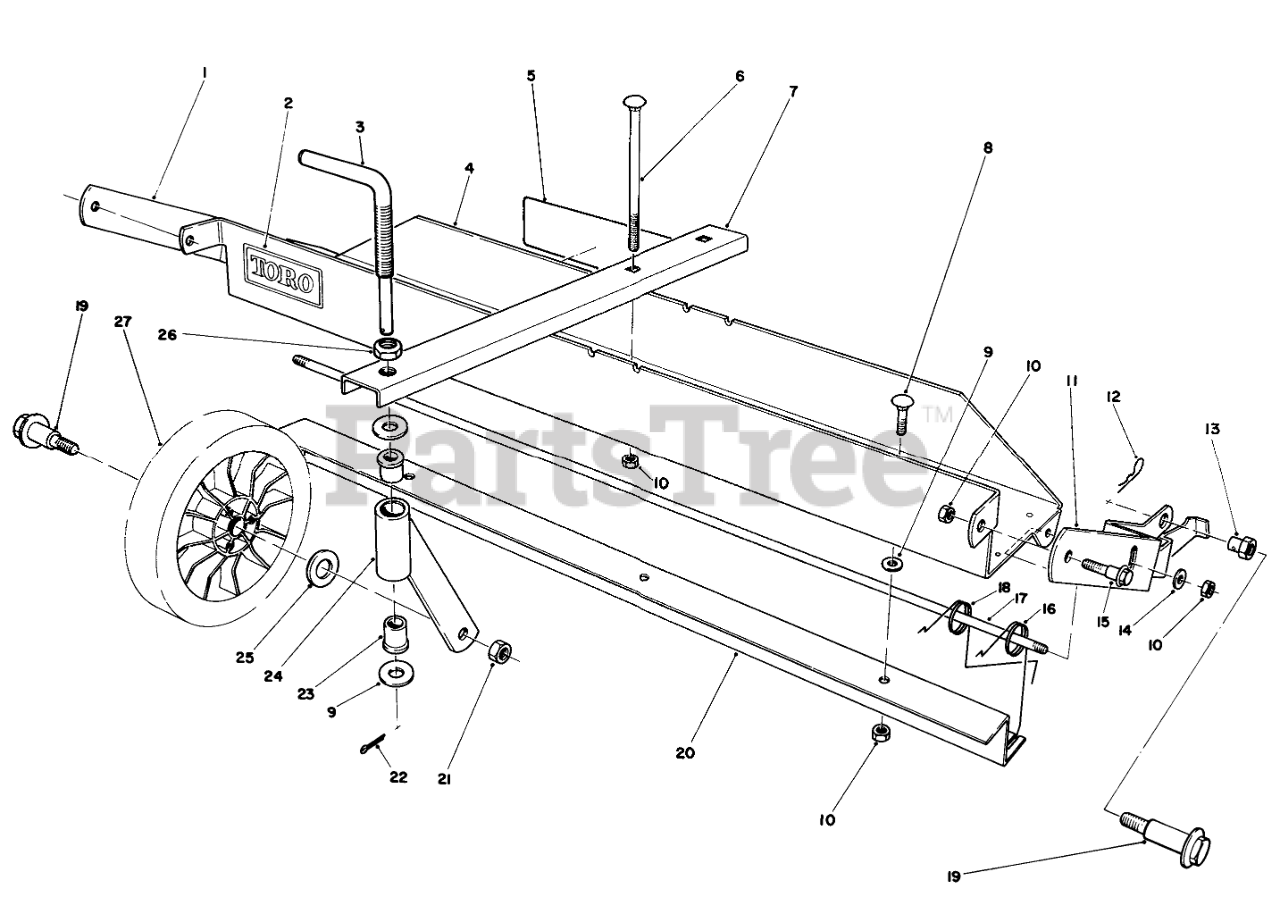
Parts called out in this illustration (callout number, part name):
1	Frame R.H.
2	Decal-Toro
3	CASTOR ADJ ROD
4	Frame-Main (Incl. Ref. #2)
5	Decal-Instruction
6	SCREW-CARR
7	Castor Frame
8	BOLT-CARR
9	WASHER-PLAIN
10	NUT-HEX, SIDE DEFORM
11	LH MTG FRAME
12	PIN-COTTER, HAIR
13	PIVOT NUT
14	WASHER-FLAT
15	BOLT-SHOULDER
16	DETHATCHER SPRING
17	SPRING SUPPORT ROD
18	DETHATCHER SPRING
19	BOLT-WHEEL
20	SPRING GUIDE STRAP
21	NUT-LOCK
22	PIN-COTTER
23	FLANGE BUSHING
24	Castor Tube & Support
25	WASHER
26	NUT-JAM
27	Wheel Assembly
